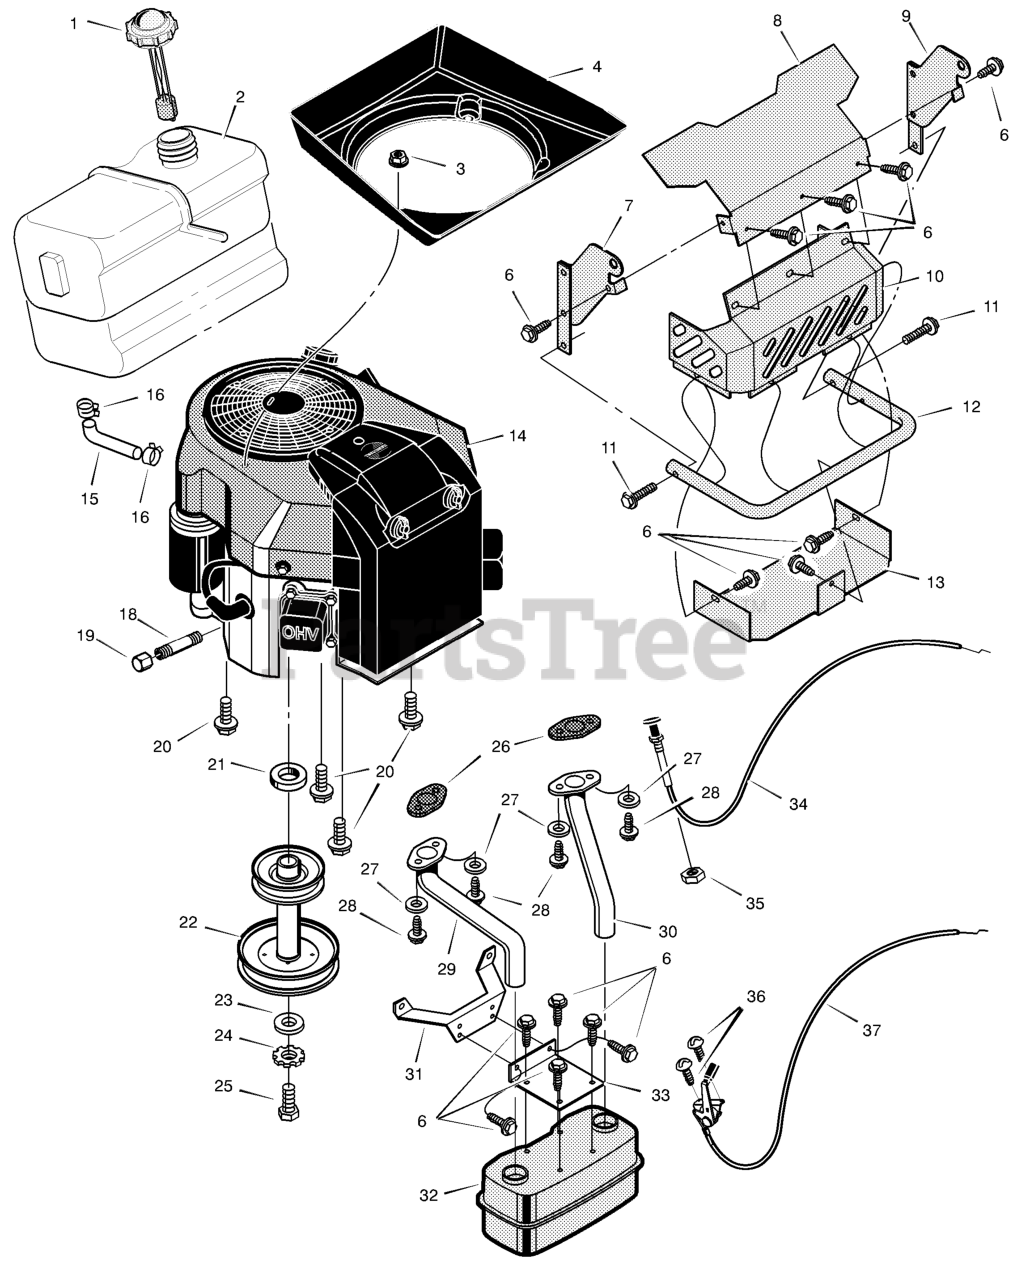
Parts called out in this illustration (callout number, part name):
1	Cap, Fuel
2	Tank, Fuel
3	Nut
4	Plenum, Air Intake
7	Assembly, Right Grille Support
8	Shield, Heat
9	Assembly, Left Grille Support
10	Shield, Heat
13	Shield, Lower
14	Engine *
15	Line, Fuel (17 inches long)
16	Clamp
18	Pipe, Oil Drain
19	Cap, Oil Drain
20	Bolt
22	Pulley, Stack
24	Lockwasher
27	Washer
28	Bolt
29	Tube, Right Exhaust
30	Tube, Left Exhaust
31	Bracket, Muffler Mount
32	Muffler
33	Bracket, Muffler
35	Nut
37	Control, Throttle
